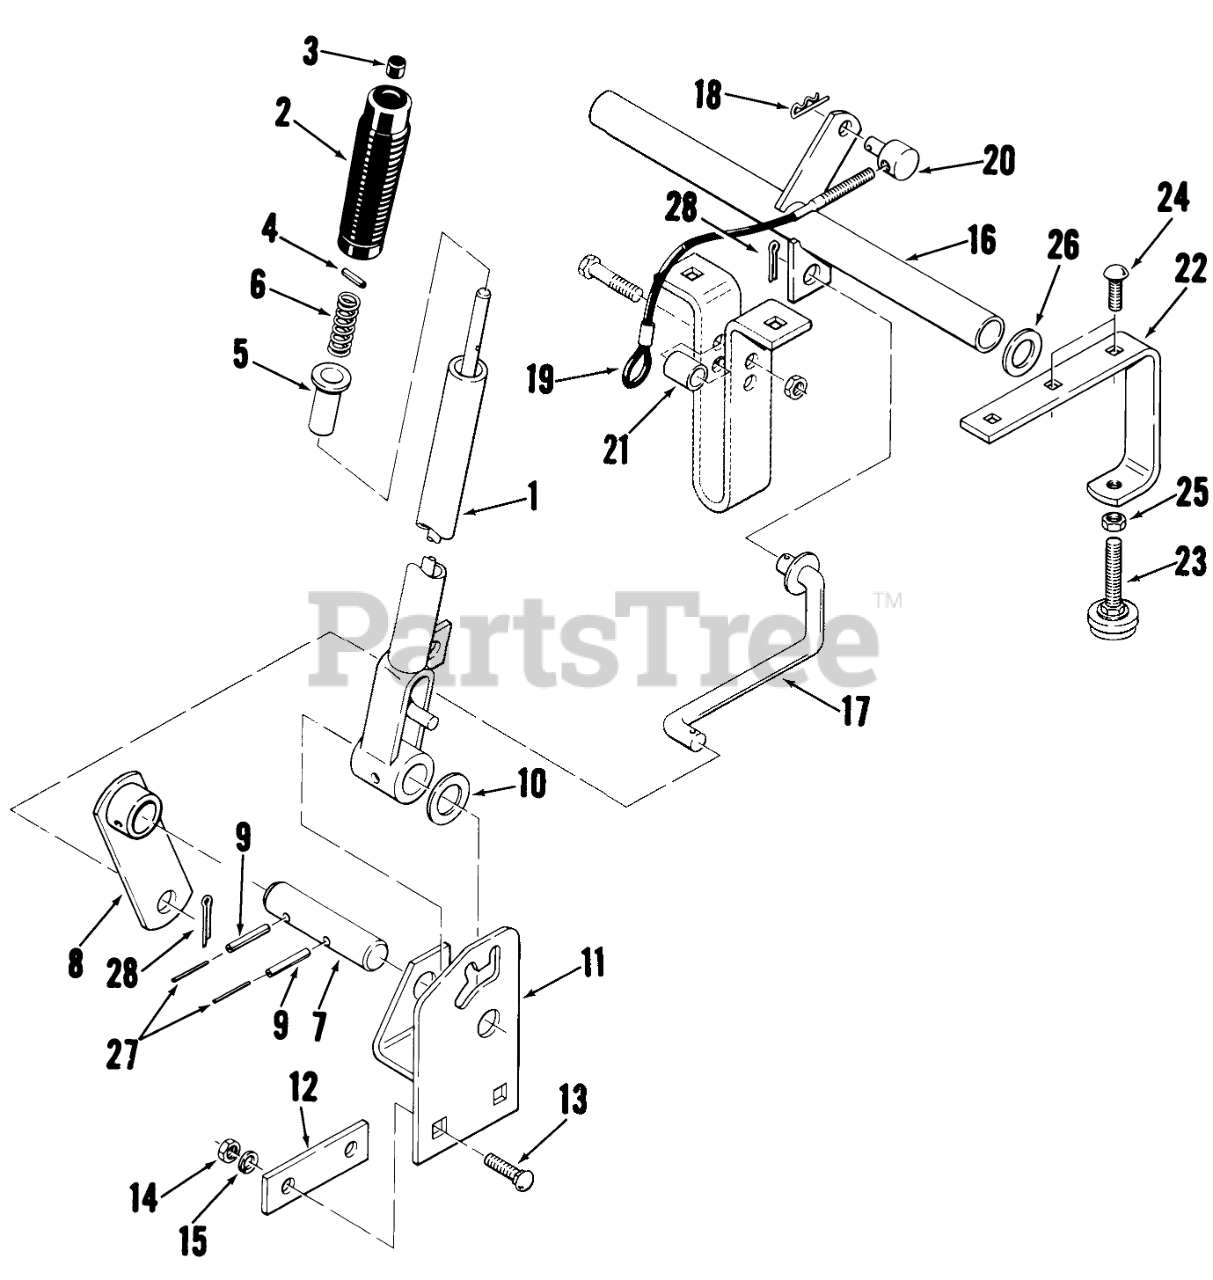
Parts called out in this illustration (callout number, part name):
1	Lift Lever
2	HANDGRIP
3	CAP-ROD, PLUNGER
4	PIN-SPIROL
5	RETAINER-SPRING
6	SPRING-COMPRESSION
7	Lift Pin
8	Lift Arm
9	ROLL PIN 1/4 X 1-1/4
10	RACE
11	ASSY-QUADRANT
12	Spacer
13	Bolt
14	Nut
15	Bolt
16	ASSY-LIFT TUBE
17	ROD-CONNECTING
18	Hairpin Cotter
19	Lift Cable
20	TRUNNION-CLUTCH ROD
21	SPACER
22	BRACKET-BUMPER
23	LEVELER MOWER
24	Bolt-Carriage
25	Nut
26	WASHER
27	PIN-SPIROL
28	Cotter Pin
